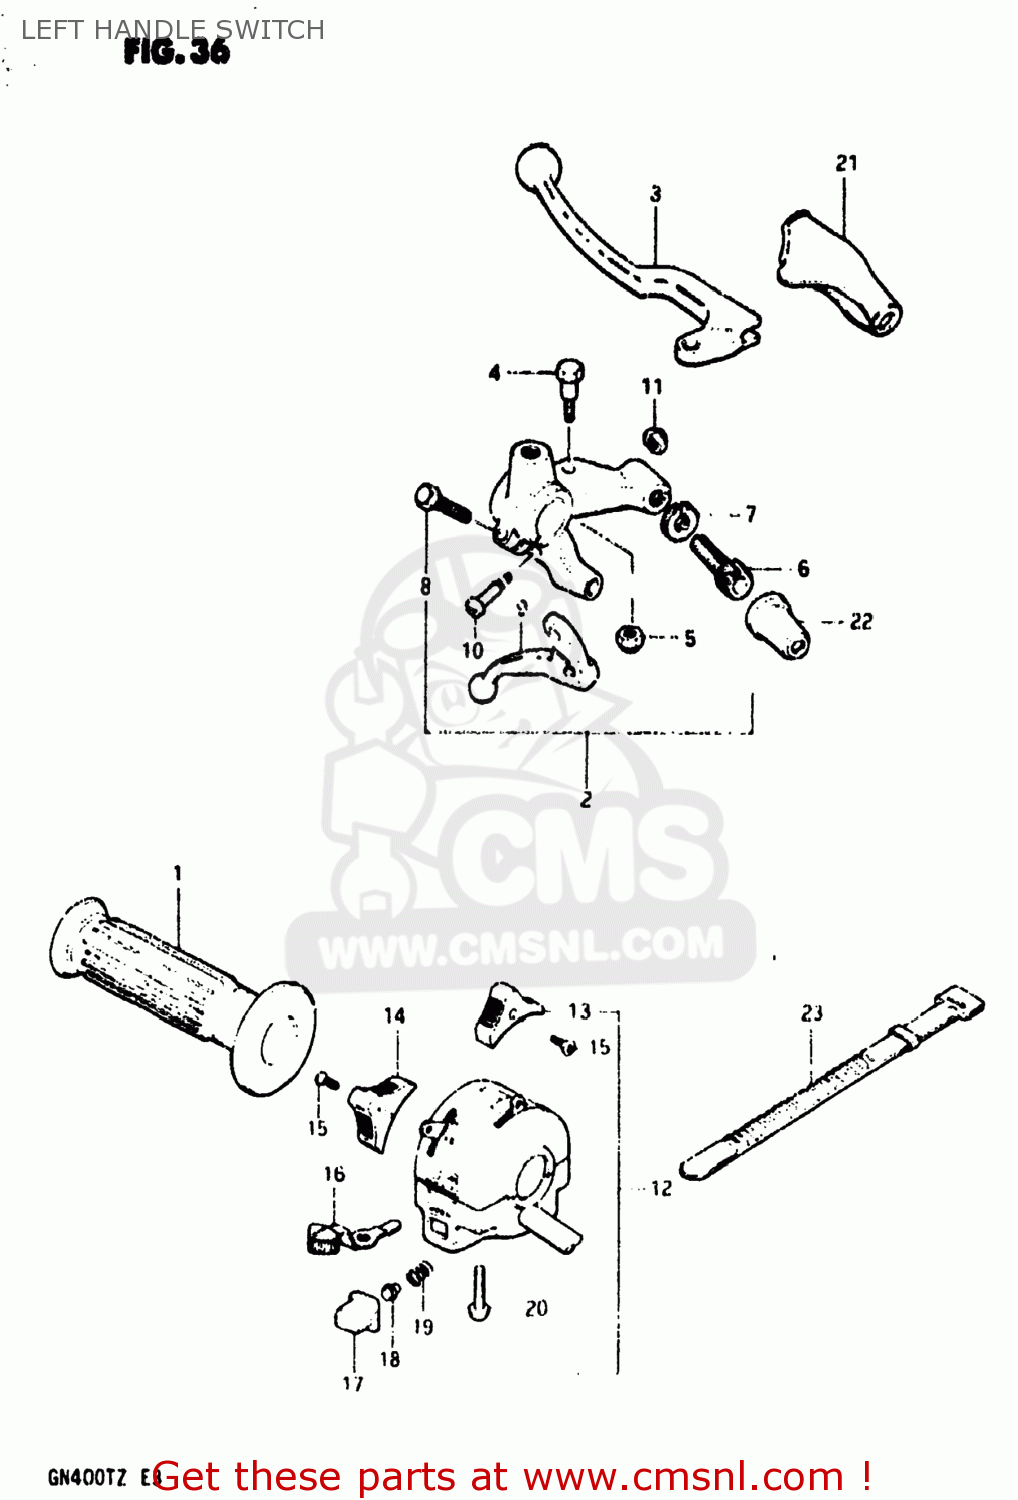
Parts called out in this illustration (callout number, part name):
1	GRIP,L
2	LEVER ASSEMBLY
3	LEVER,CLUTCH
4	BOLT,LEVER
5	NUT 6MM
6	ADJUSTER,CABLE
7	NUT,CABLE ADJUSTER
8	BOLT,CLUTCH LEVER HOLDER
9	LEVER,DECOMPRESSION
10	BOLT,LEVER
11	NUT,LEVER BOLT
12	SWITCH ASSEMBLY,HANDLE,LEFT
13	KNOB,LIGHTING SWITCH
14	KNOB,DIMMER SWITCH
15	SCREW
16	KNOB,TURNSIGNAL
17	BUTTON,HORN
18	CONTACT
19	SPRING
20	SCREW
21	COVER,CLUTCH LEVER
22	BOOT,CLUTCH CABLE
23	CLAMP(L:120)
